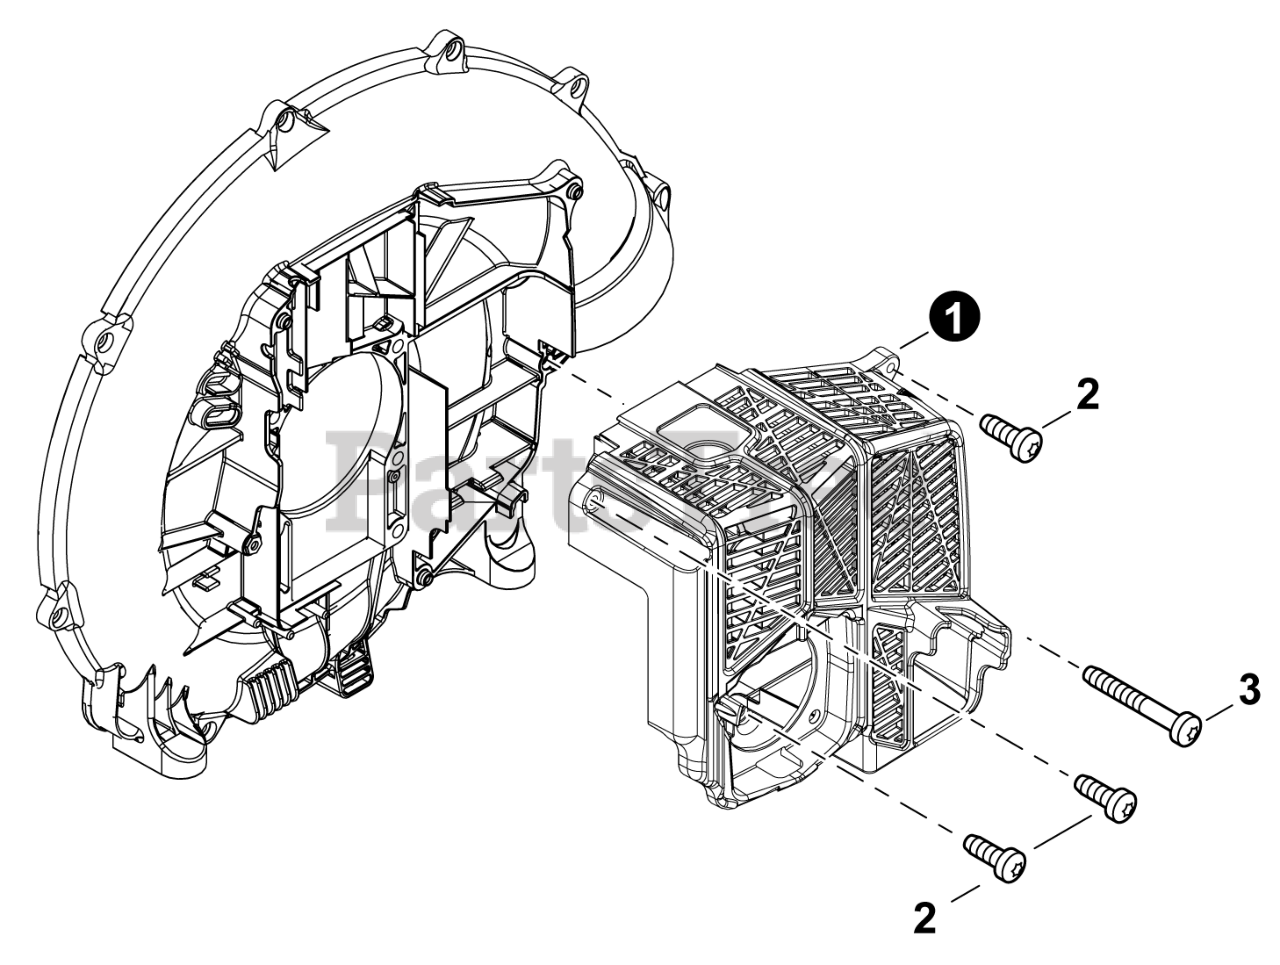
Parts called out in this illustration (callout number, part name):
1	COVER, ENGINE
2	BOLT, TORX 5x20
3	BOLT, TORX 5x55
